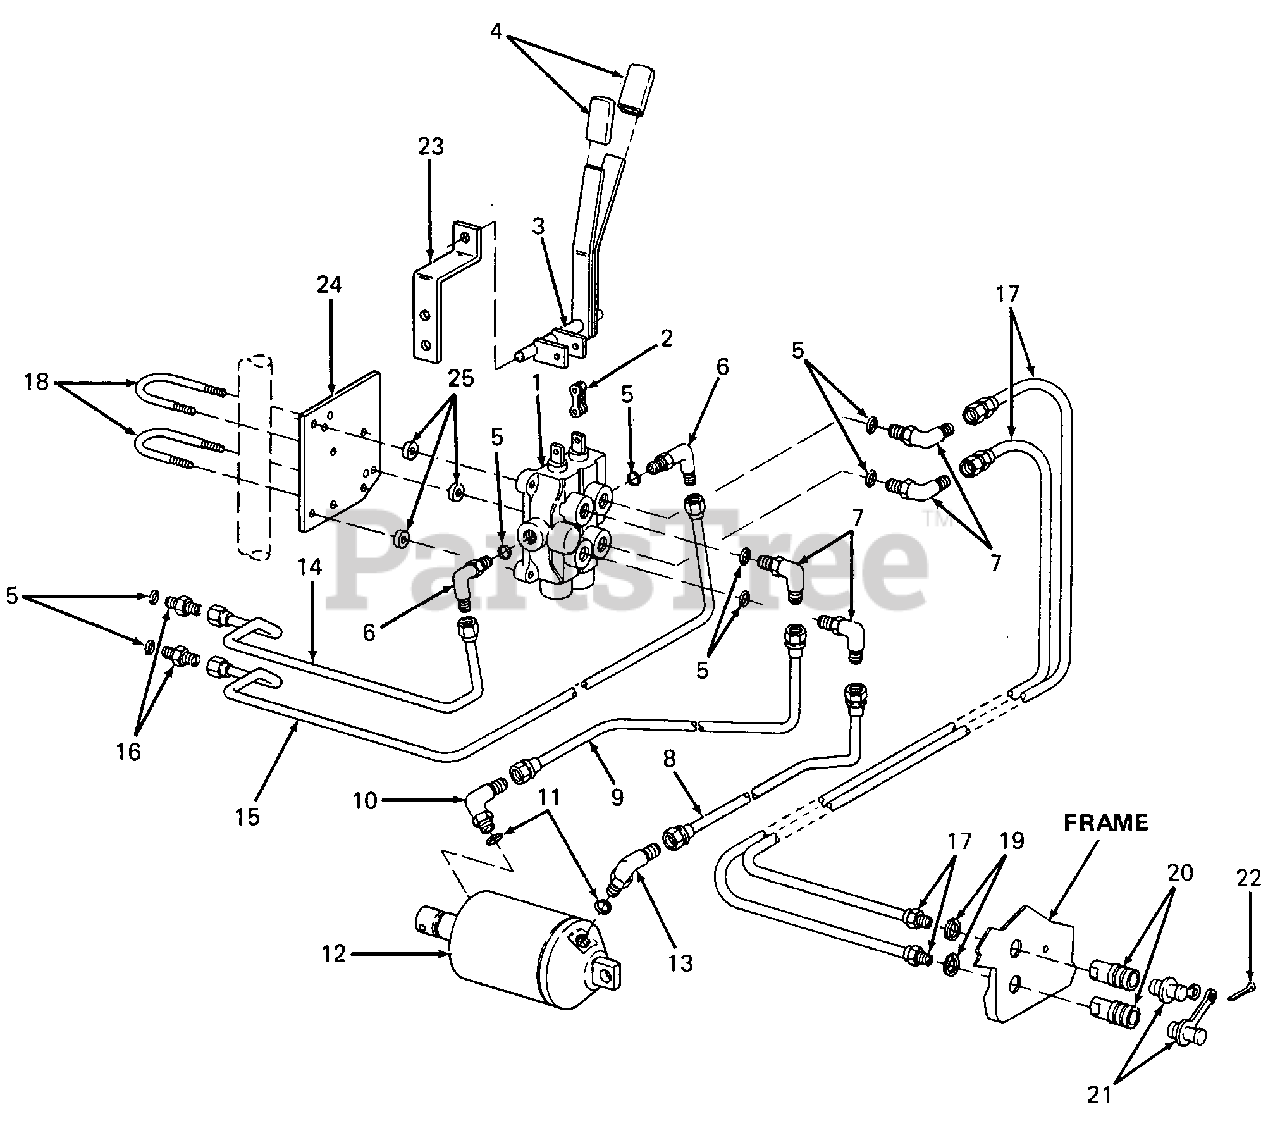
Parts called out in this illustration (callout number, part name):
1	Valve Assy, 2 Spool Control
2	Link, Chain
3	Handle Assy, 2 Spool Valve
5	O-Ring, 3/8 OD Tube
6	Elbow, 90 Degree Tube
7	Elbow, Reducer, 3/8 to 1/4
8	Hose, Extending
9	Hose, Retracting
10	Elbow, 90 Degree w/O-Ring
11	O-Ring, 1/4 OD Tube
12	Cylinder, Hydraulic
13	Elbow, 45 Degree w/O-Ring
14	Tube Assy, Return
15	Tube Assy, Pressure
16	Connector, 37 Degree Tube
17	Hose, Pressure Supply
19	Ring, External Retaining
20	Coupling Body, Hydraulic
21	Plug, Protective
22	Pin, Cotter, 3/16 X 3/4 Lg
23	Support, Valve Handler
24	Plate, Valve Support
25	Spacer, .267 X .406 X .375 Lg
